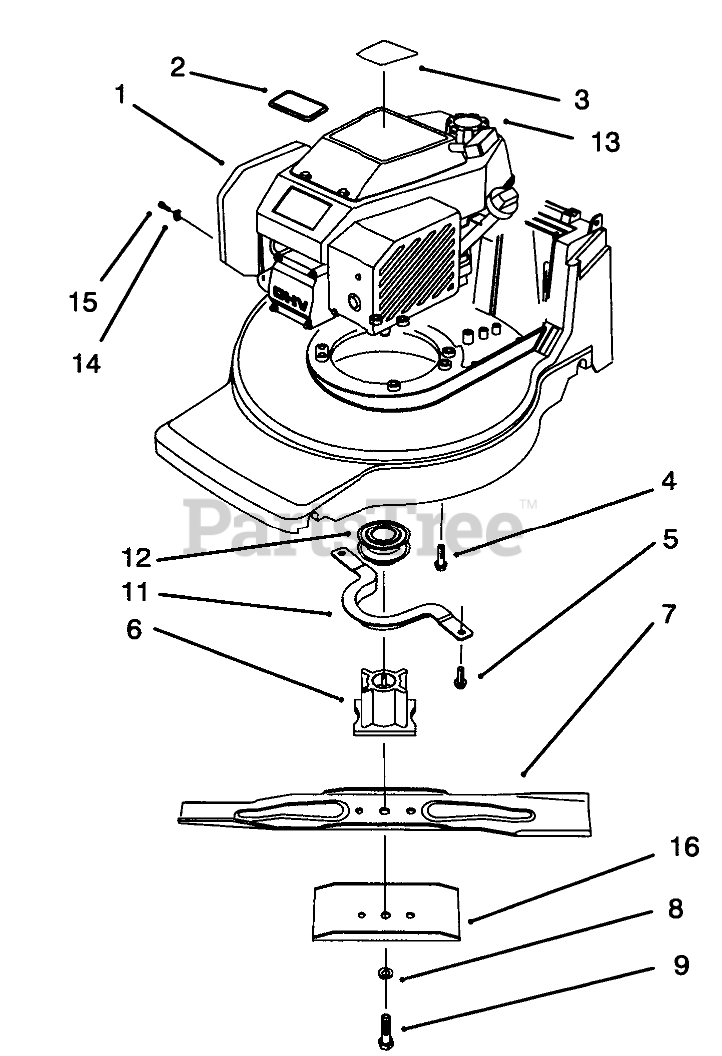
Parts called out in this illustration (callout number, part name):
1	ENG ASM-GTS 150 NC
2	PLATE-LOGO
3	DECAL - ENGINE
4	SCREW-HWH
5	SCREW-HWH
6	BLADE RETAINER - 25 MM
7	Blade
8	WASHER-LOCK
9	BOLT-BLADE
11	Guide-Belt
12	PULLEY-DRIVE, ZONE START
13	GAS CAP ASM
14	CLAMP-CASING
15	CLAMP SCREW F/W ENGINE
16	Stiffener Blade
